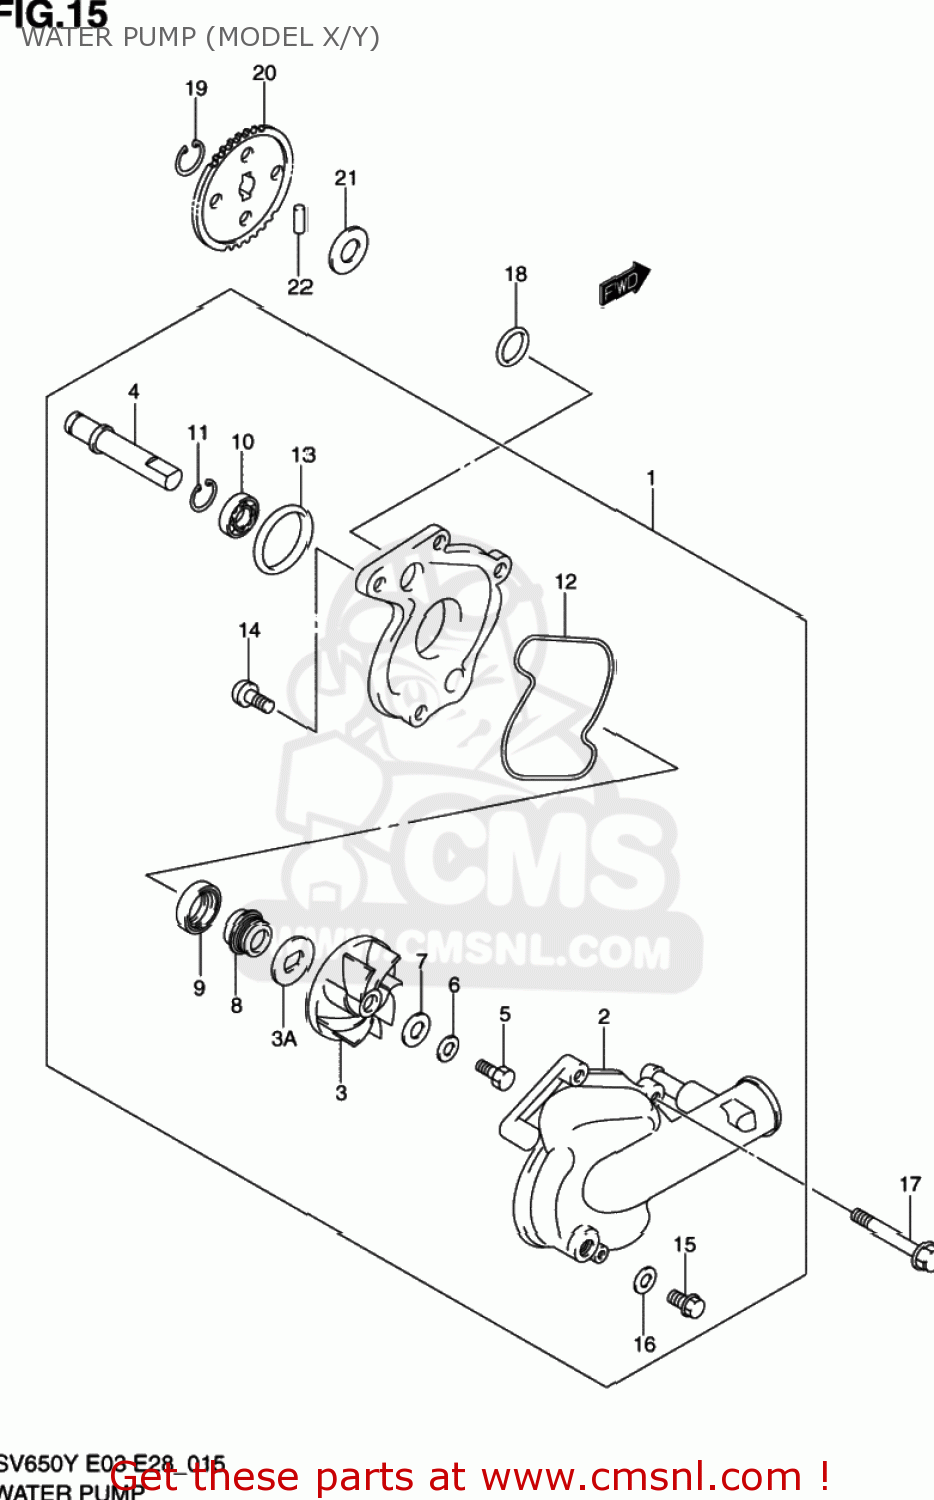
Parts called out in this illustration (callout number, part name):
1	PUMP ASSEMBLY,WATER
2	CASE,WATER PUMP
3	IMPELLER,WATER PUMP
3A	WASHER,IMPELLER
4	SHAFT,WATER PUMP
5	BOLT(6X13)
6	WASHER
7	GASKET(6X15X2.2) (NAS)
8	SEAL,MECHANICAL
9	SEAL,OIL(10X21X5)
10	BEARING(10X26X8)
11	E RING
12	O RING
13	O RING,WATER PUMP HOLDER
14	SCREW 6X16
15	BOLT,DRAIN
16	GASKET 8.2X14X1 (NAS)
17	BOLT(6X50)
18	O RING(D:2.4,ID:21.8)
19	CIRCLIP,10MM
20	GEAR,WATER PUMP DRIVEN
21	SHIM(10X18X0.5)
22	ROLLER(4X13.8)
